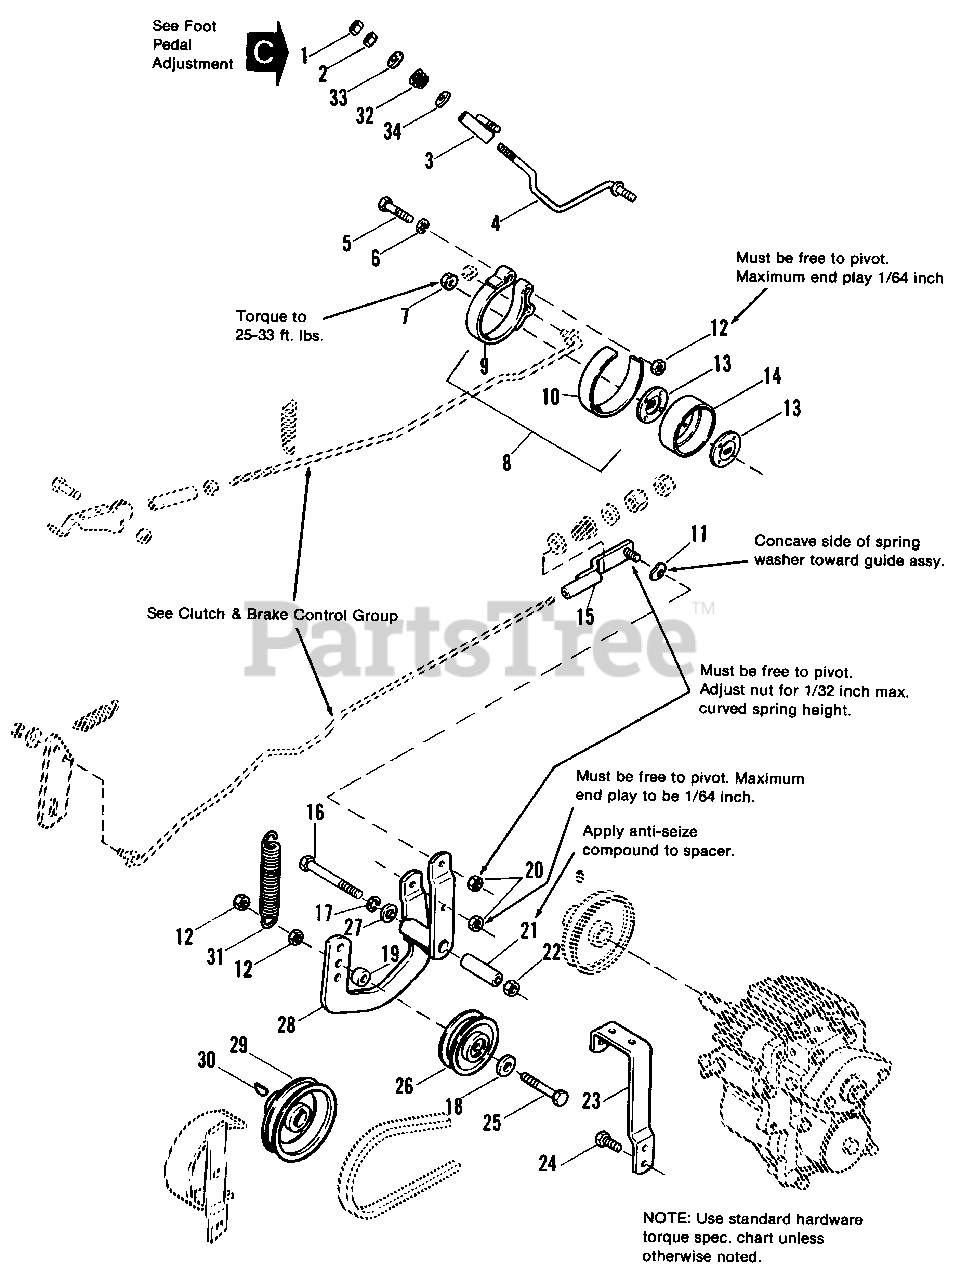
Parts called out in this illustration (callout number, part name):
1	LOCKNUT, Hex, Esna, 3/8-16
2	NUT, Hex, Full, 3/8-16
3	GUIDE ASSY., Rod
5	CAPSCREW, Hex Hd., 3/8-16 x 1-3/4
6	LOCKWASHER, 3/8
7	LOCKNUT, Hex, Flange, 7/16-14
8	BAND ASSY., Brake (Incl. Ref. Nos. 9 & 10)
11	WASHER, Curved Spring
12	LOCKNUT, Hex, 3/8-16
13	WASHER, Special
14	DRUM, Brake
15	GUIDE ASSY., Rod
16	CAPSCREW, Hex Hd., 7/16-14 x 3-3/4
17	LOCKWASHER, 7/16
18	WASHER, Plain, 3/8 std.
20	LOCKNUT, Hex, 5/16-18
22	NUT, Hex, Full, 7/16-14
24	SCREW, Self-tapping, 3/8 x 3/4
25	CAPSCREW, Hex Hd., 3/8-16 x 2-1/4
26	PULLEY ASSY., Idler (Plastic)
27	WASHER, 3/8
28	LEVER ASSY., Idler
29	PULLEY
30	KEY
32	SPRING, Cone
34	WASHER
